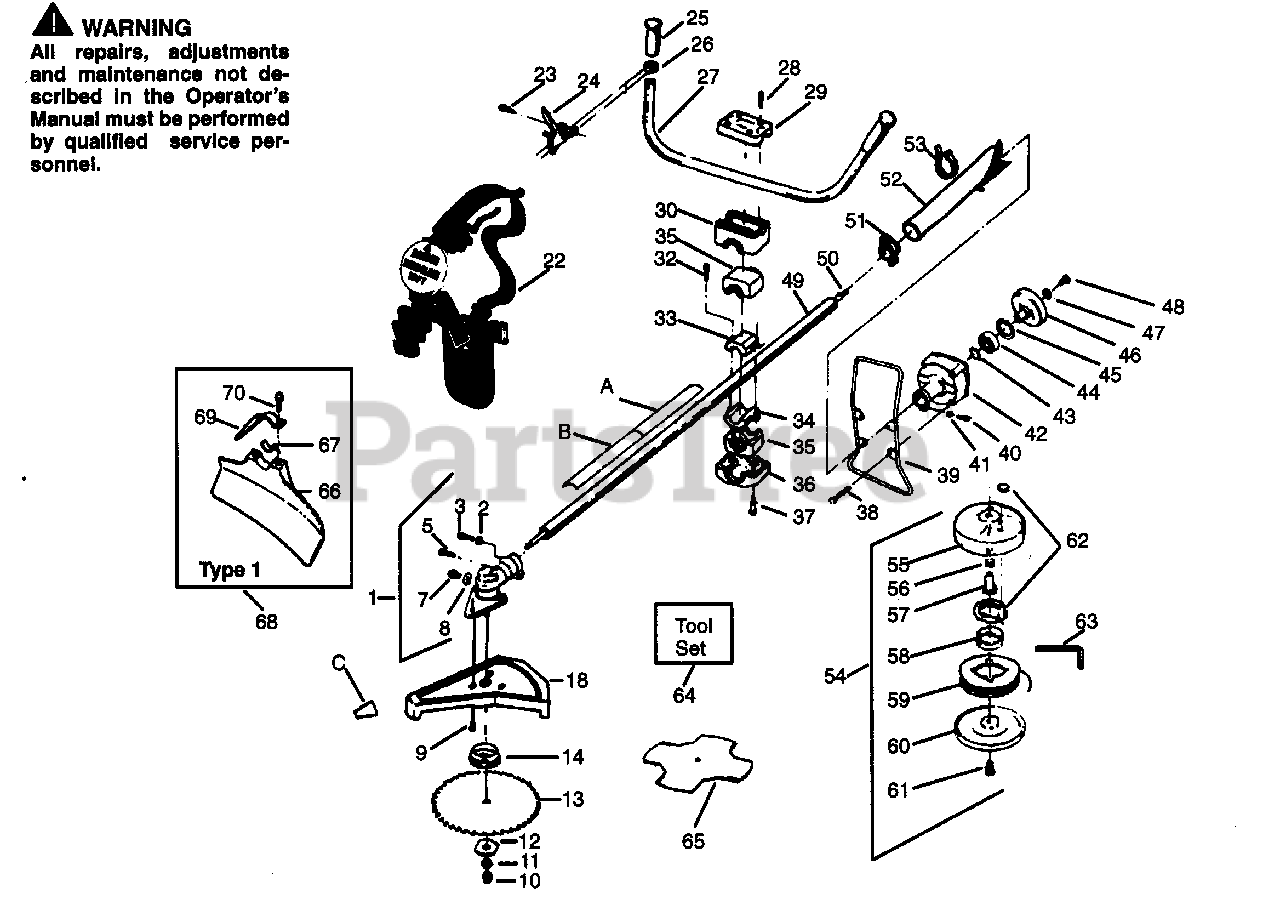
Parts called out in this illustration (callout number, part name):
1	Gear Case Ass'y.
2	Lockwasher
12	Lower Adaptor
13	Brush Blade-10"
14	Upper Adaptor
18	Shield Ass'y. XR-200 & YP200 Type Il;PP200 Type 1
22	Shoulder Strap
24	Throttle Control
25	Handlebar Grip
26	Throttle Collar
27	Handlebar Ass'y. (Inc. #25 & 26)
29	Handlebar Clamp
30	Handlebar Clamp
33	Metal Fitting
34	Metal Fitting
35	Isolator
36	Handlebar Clamp
39	Wire Stand
41	Lock Washer
42	Clutch Case
43	Snap Ring
45	Snap Ring
46	Clutch Drum
49	Drive Shaft Hsg.
50	Drive Shaft
51	Bracket Ass'y.
53	Tie Strap
54	Cutting Head Ass'y. (Inc. #55-63)
56	Line Saver
57	Drive Adaptor
59	Spool w/Line
62	Release Button (Inc. Lock Ring)
63	Hex Wrench
64	Tool Set
65	Weed Blade-Optional
68	Shield Ass'y.
A	Shaft Warning Decal (Upper)
B	Shaft Warning Decal (Lower)
C	Shield Warning Decal
